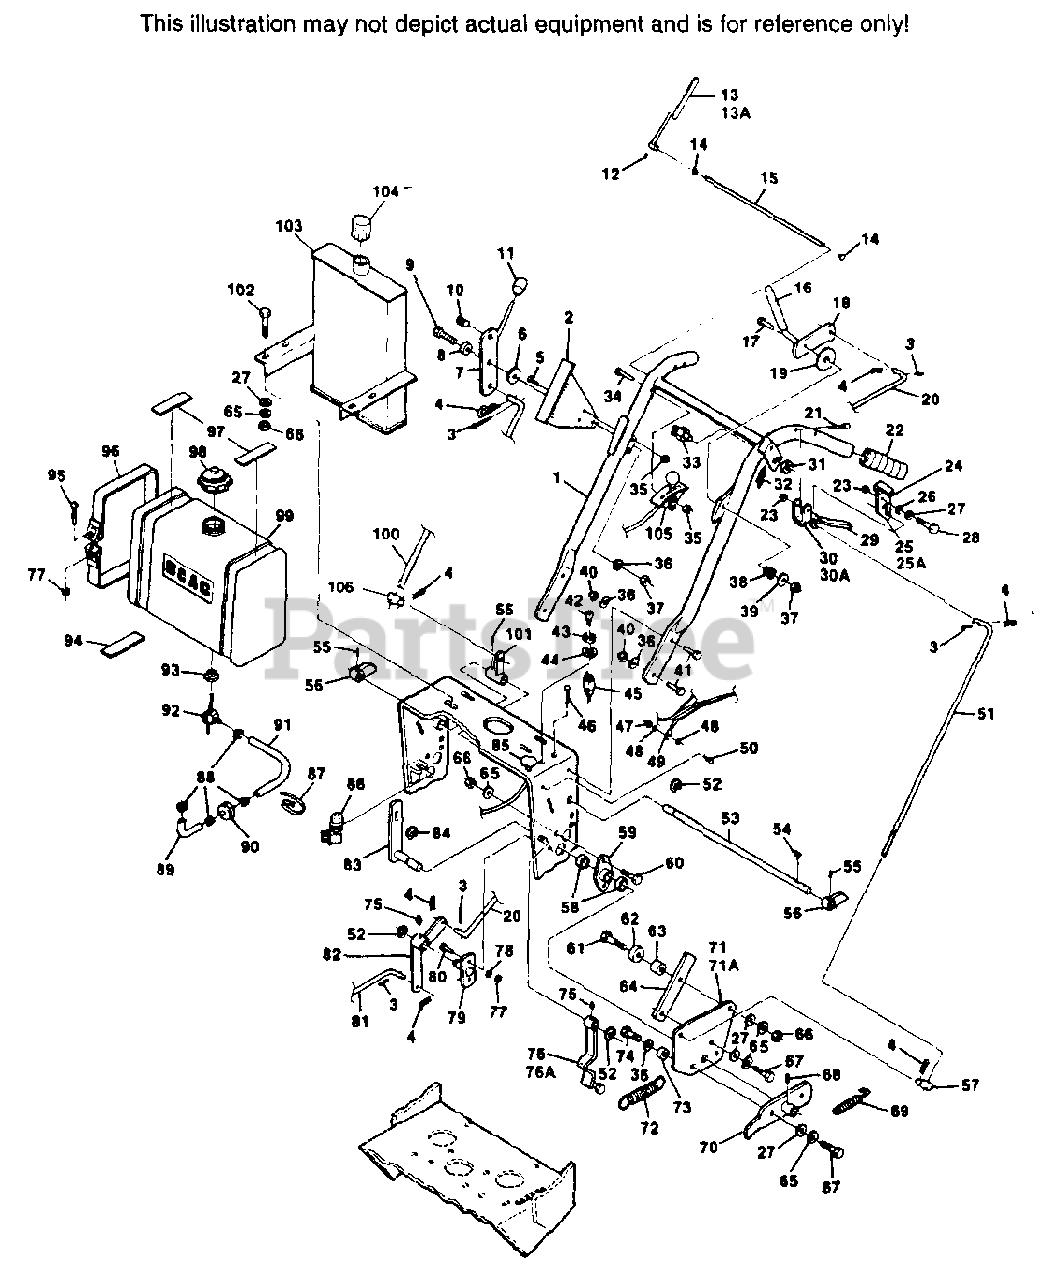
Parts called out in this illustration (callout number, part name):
1	HANDLE ASSY.
2	QUADRANT, SPEED CONTROL
4	HAIR PIN, SMALL
5	CAPSCREW, 1/4-20 X .75 FLAT HD. HEX SOCKET
6	FLAT WASHER, .656 ID X 1.312 OD X .095
7	SPEED ADJUSTMENT LEVER
8	BUSHING, SPEED ADJUSTMENT LEVER
10	BALL PLUNGER
11	KNOB, SPEED ADJUSTMENT LEVER
12	SET SCREW, 1/4-28 X 1 KNURLED CUP POINT
13	SAFETY INTERLOCK, HAND GRIP - LH
13A	SAFETY INTERLOCK, HAND GRIP - RH
14	BUSHING, CONTROL ROD
15	ROD, CONTROL PIVOT
16	GRIP, CUTTER DECK ENGAGE
18	BLADE CLUTCH LEVER ASSY.(INCLUDES GRIP)
19	FLAT WASHER, 3/8 X 2 X 16 GA.
20	ROD, BELT CLUTCH - CUTTER
21	CARRIAGE BOLT, 5/16-18 X 2-1/2, RD. HD. SQ.
22	GRIP, HANDLE
23	HEX NUT, 5/16-18, ELASTIC STOP
24	GRIP, NEUTRAL LATCH - RH
24	GRIP, NEUTRAL LATCH - LH
25	NEUTRAL LATCH - RH(INCLUDES GRIP)
25A	NEUTRAL LATCH - LH(INCLUDES GRIP)
26	CURVED SPRING WASHER
29	GRIP, STEERING CONTROL
30	STEERING CONTROL LEVER - RH(INCLUDES GRIP)
30A	STEERING CONTROL LEVER - LH(INCLUDES GRIP)
31	HEX NUT, 9/16-18 SPRING STEEL
32	SPRING, GRIP RETURN
33	SWITCH, INTERLOCK(GOLD COLORED)
35	HEX NUT, 1/4-20 ELASTIC STOP
37	HEX NUT, 3/8-16 ELASTIC STOP
38	SPRING, COMPRESSION
39	FLAT WASHER, 25/64 X 15/16 X 12 GA.
40	HEX NUT, 3/8-16 ELASTIC STOP
42	KEY, IGNITION
43	HEX NUT, 5/8-32
44	LOCKWASHER, 5/8 INTERNAL TOOTH
45	SWITCH, IGNITION
48	LOCKWASHER, #10 EXTERNAL TOOTH
49	WIRE HARNESS
50	MACHINE SCREW, #10-32 X 1/2 PHILLIPS
51	CONTROL ROD, STEERING
52	RETAINING RING, 5/8 EXT. - "E"
53	JACKSHAFT, SPEED CONTROL
54	KEY, 1/8 X 1/2 WOODRUFF #3
55	SETSCREW, HEX SOCKET KNURLED CUP PT.,
56	CAM, SPEED CONTROL(INCLUDES SETSCREW)
57	SWIVEL JOINT, STEERING ROD
58	BUSHING
59	PIVOT, PUMP CONTROL SHAFT(INCLUDES BUSHINGS
61	BOLT, HEX HD., 5/16-18 X 1-3/4 FULL THREAD
62	BEARING, SPEED CONTROL
63	SPACER, SPEED CONTROL BEARING
64	BAR, SPEED CONTROL ADJUSTMENT
68	DRIVE PIN, 5/32 X 7/8 TYPE U
69	SPRING, NEUTRAL RETURN
70	HANDLE, NEUTRAL ADJUSTMENT
71	BELLCRANK, LH CONTROL
71A	BELLCRANK, RH CONTROL
72	SPRING, SPEED CONTROL
73	BEARING, NEUTRAL RETURN
75	GREASE FITTING, STRAIGHT 1/4-28
76	NEUTRAL CAM, RH(INCLUDES GREASE FITTING)
76A	NEUTRAL CAM, LH(INCLUDES GREASE FITTING)
79	BELLCRANK PIVOT WELDMENT
81	ROD, BLADE CLUTCH - LOWER
82	BELLCRANK, CUTTER ENGAGE(INCLUDES GREASE
83	SHAFT, LH PUMP CONTROL
84	RETAINING RING, 1/2" EXT. - "E"
86	SWITCH, NEUTRAL
87	CABLE TIE
88	CLAMP, FUEL HOSE
92	VALVE, FUEL SHUT-OFF
93	BUSHING
94	PAD, RUBBER - FUEL TANK - LOWER
95	MACHINE SCREW, 1/4-20 X 2 ROUND HD. SLOTTED
96	STRAP, FUEL TANK
97	PAD, RUBBER - FUEL TANK - UPPER
98	FUEL TANK CAP
99	FUEL TANK ASSEMBLY(INCL. ITEMS 92, 93, 98
100	ROD, TRACTION CONTROL
101	BELLCRANK, SPEED CONTROL
102	CARRIAGE BOLT, 5/16-18 X 1 RD. HD. SQ. NK.
103	OIL RESERVOIR
104	CAP, OIL RESERVOIR
106	SWIVEL JOINT, SPEED CONTROL ROD
